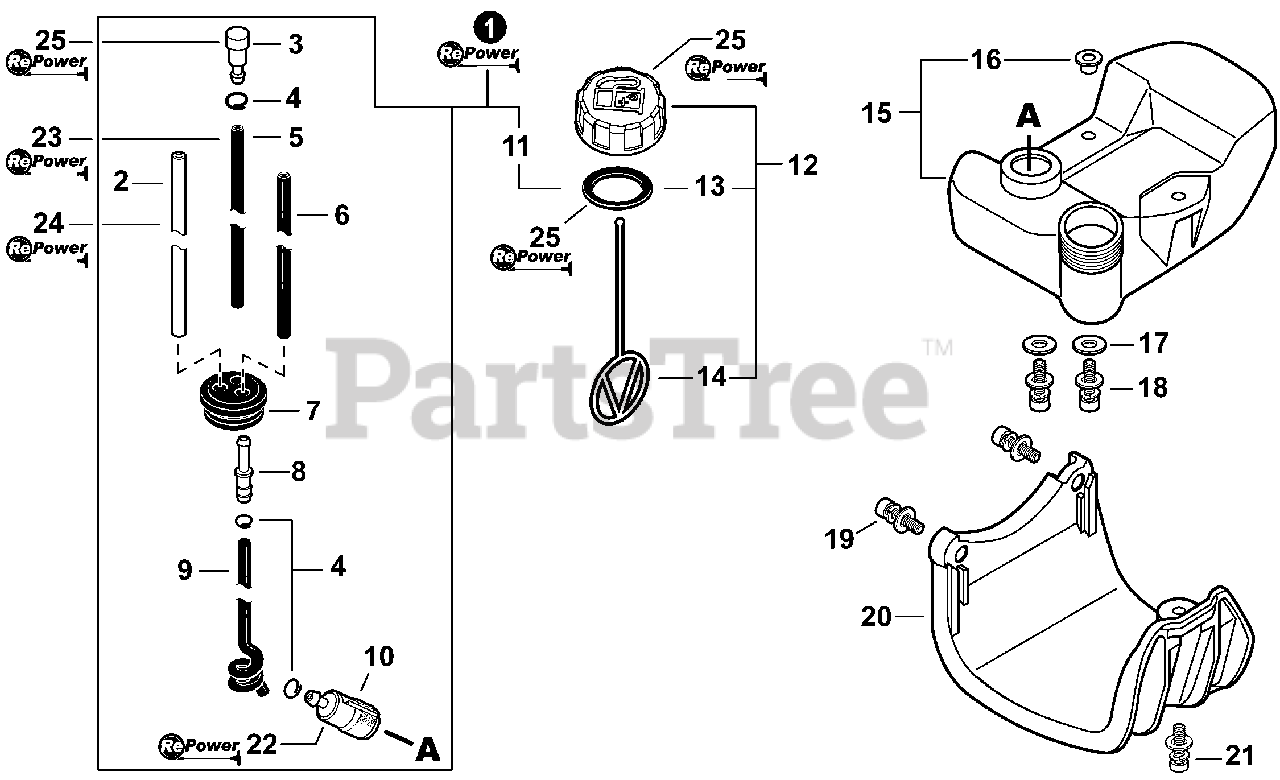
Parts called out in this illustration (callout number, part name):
1	FUEL SYSTEM KIT
2	PIPE, FUEL 3×6×80 CLEAR
3	VENT ASSY
4	CLIP Ø6.5 MM
5	PIPE 3×6×115 BLACK
6	PIPE, FUEL 3×5×74 BLACK
7	GROMMET, FUEL
8	CONNECTOR, PIPE Ø5ר3.5
9	PIPE, FUEL 3×6×105
10	FILTER, FUEL
11	GASKET, FUEL CAP
12	CAP ASSY, FUEL
13	GASKET, FUEL CAP
14	CONNECTOR, CAP L= 100 MM
15	TANK, FUEL
16	COLLAR 5
17	WASHER 5.5×12×0.8
18	BOLT 5×16
19	BOLT 5×22
20	GUARD, FUEL TANK
21	SCREW 5×20
22	TUNE-UP KIT - REPOWER
23	BULK PIPE - 3×6 MM BLACK (4 PIECES×2 M)
24	BULK PIPE - 3×6 MM CLEAR (4 PIECES×2 M)
25	CAP/VENT KIT - REPOWER
